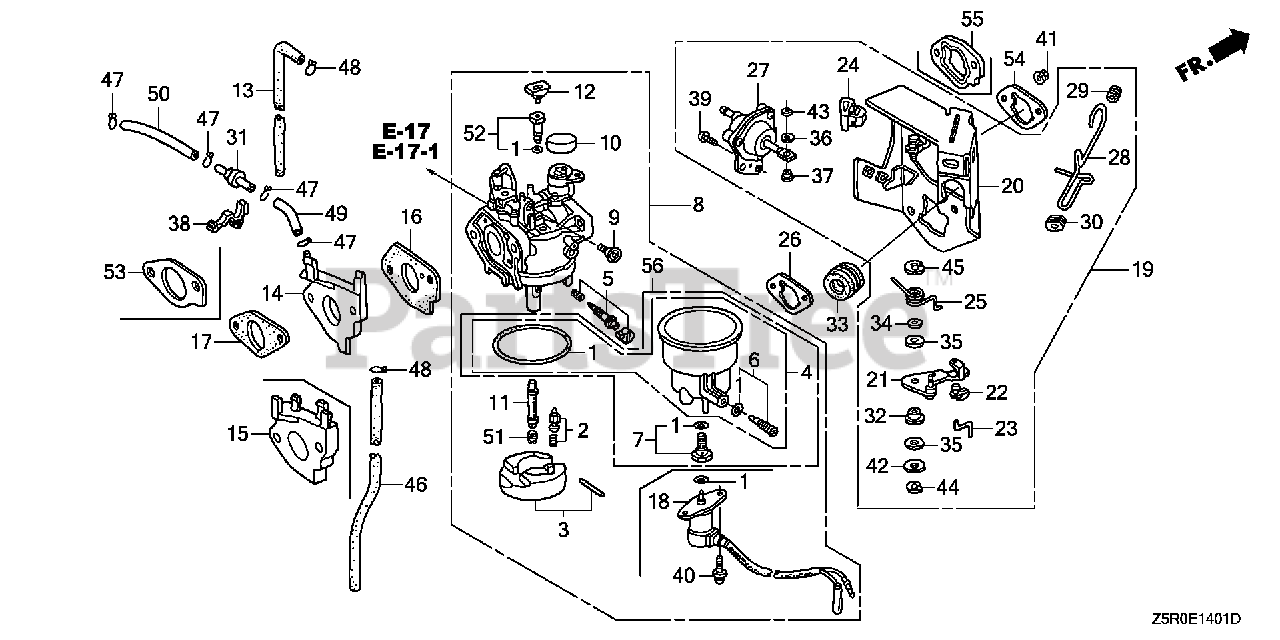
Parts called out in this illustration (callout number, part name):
1	GASKET SET
2	VALVE SET, FLOAT
4	CHAMBER SET, FLOAT
6	SCREW SET, DRAIN (CARBURETOR NO.)
8	CARBURETOR ASSY. (BE87E C)
8	CARBURETOR ASSY. (BE89E B)
9	SCREW, THROTTLE STOP
10	CAP, CHOKE DUST
11	NOZZLE, MAIN
12	COLLAR, SETTING
14	INSULATOR, CARBURETOR
16	GASKET, CARBURETOR
17	GASKET, INSULATOR
18	VALVE ASSY., SOLENOID
19	STAY ASSY., MANUAL CHOKE
20	STAY, SOLENOID
21	LEVER, CHOKE
22	JOINT, ROD
23	ROD, CHOKE
24	STOPPER, CHOKE ROD
25	SPRING, MANUAL CHOKE
26	GASKET, AIR CLEANER
27	DIAPHRAGM ASSY.
28	ROD, CHOKE CONTROL
29	GROMMET, CHOKE ROD
30	GUIDE, CHOKE ROD
31	VALVE, DASHPOT CHECK
32	BUSH, ARM PIVOT
33	GROMMET, FENDER
34	WASHER, CHOKE LEVER
35	SEAL, CHOKE LEVER
36	WASHER, THRUST (2.7X8)
37	COLLAR, LEVER
39	SCREW, PAN (5X12)
40	SCREW-WASHER (5X12)
41	NUT, FLANGE (6MM)
42	WASHER, PLAIN (5MM)
43	E-RING (2MM)
44	E-RING (4MM)
45	E-RING (7MM)
47	CLIP, TUBE (B7)
49	BULK HOSE, VACUUM (3.5X8000) (3.5X75)
50	BULK HOSE, VACUUM (3.5X8000) (3.5X130)
51	JET, MAIN (#98)
51	JET, MAIN (#100)
51	JET, MAIN (#102)
52	JET SET, PILOT (#45)
54	GASKET, AIR CLEANER
